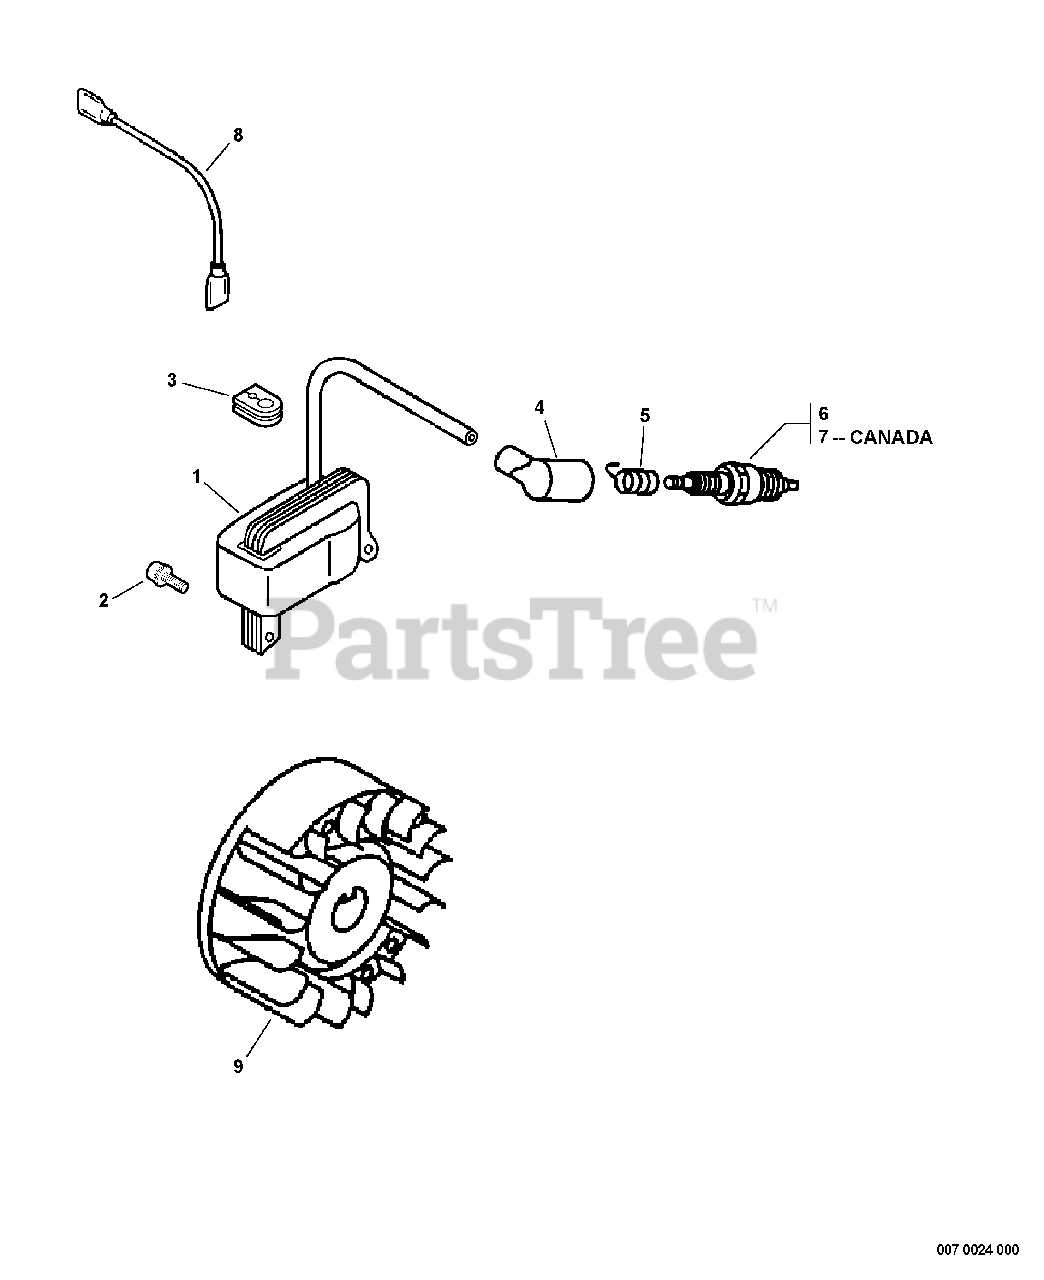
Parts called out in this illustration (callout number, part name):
1	COIL, IGNITION
2	SCREW - 5X16
4	CAP, SPARK PLUG
5	TERMINAL, SPARK PLUG CAP
6	SPARK PLUG -- BPM-8Y
7	SPARK PLUG -- BPMR-8Y
8	LEAD - IGNITION
9	FLYWHEEL
10	RePower TUNE-UP KIT
11	RePower TUNE-UP KIT
